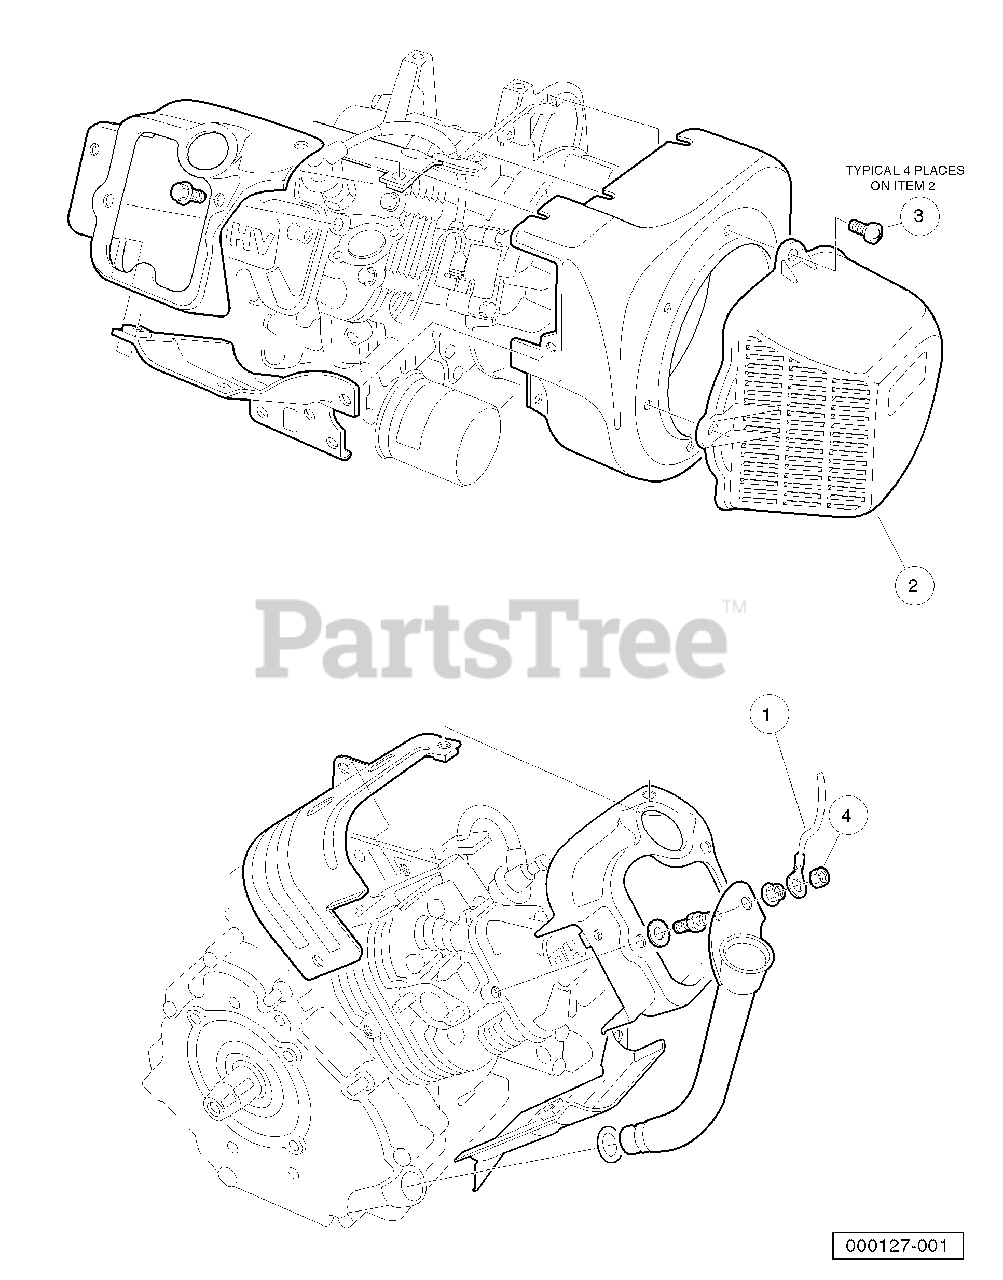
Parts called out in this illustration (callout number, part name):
1	Wire Assembly, #10, Uninsulated
2	Shroud, Fan
3	Screw, M6-1.00 X 10mm Pan Hd
4	Locknut, M6-1.00 Nylon Insert
5	Engine, FE400
